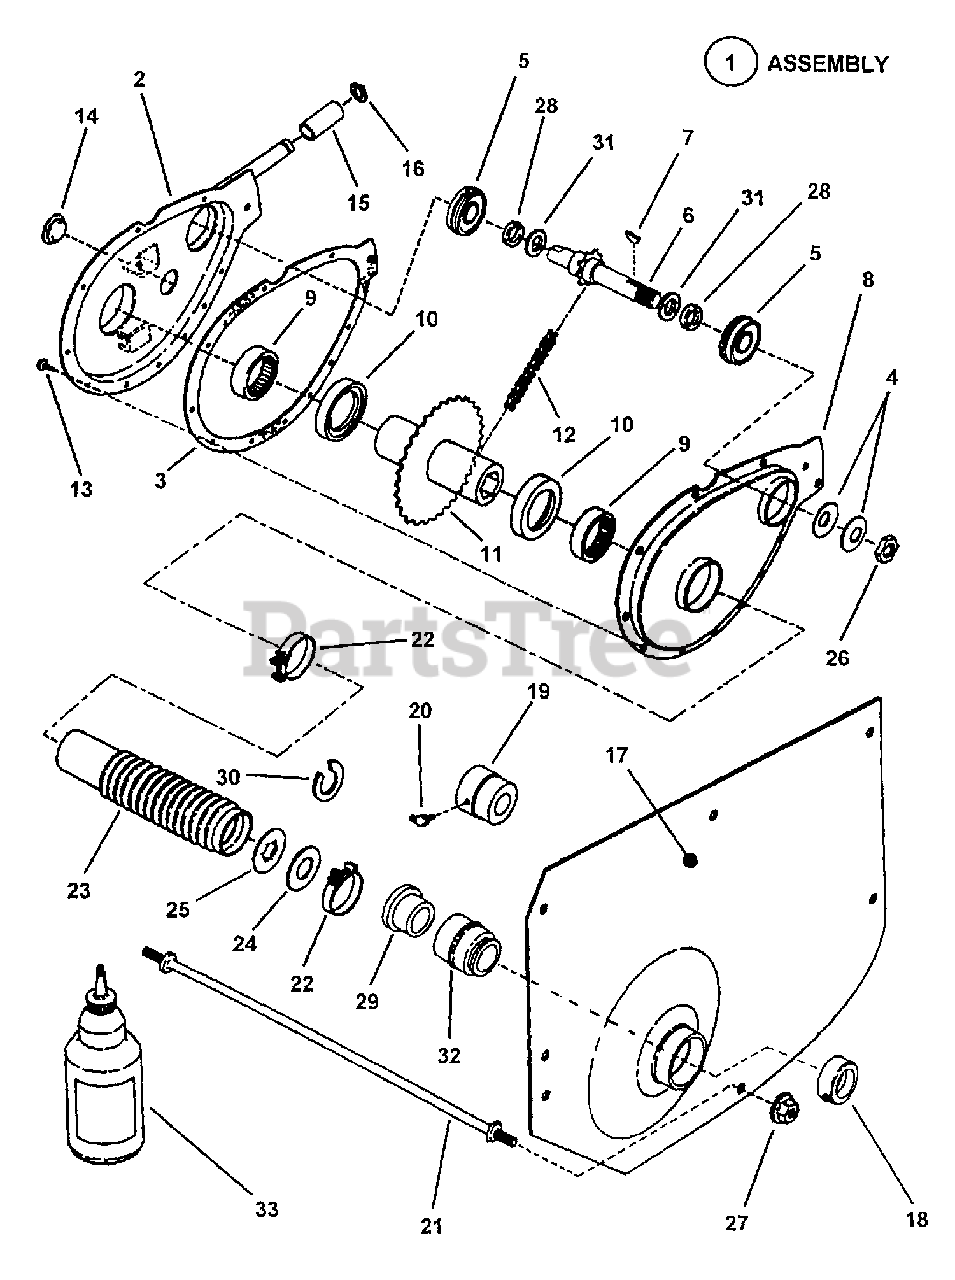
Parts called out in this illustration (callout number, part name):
1	ASSEMBLY, Chain Case
2	CASE, Sprocket
3	GASKET, Case Cover
4	WASHER, .640 I.D. Belleville
5	BEARING, Ball
6	SPROCKET & SHAFT
7	KEY, 1/8 x 5/8" Woodruff
8	COVER, Chain Case
9	BEARING, Needle
10	WASHER, Nylon Thrust
11	HUB & SPROCKET
12	CHAIN
13	SCREW, #10-24 x 1/2" Hex Washer Self-Tap (Torx)
14	PLUG, Oil Fill & Check
15	ROLLER
16	RING, 1/2" Heavy Duty External Retaining
17	FENDER, Left Hand
17	ASSEMBLY, Left Hand Fender
18	COLLAR, Lock
19	BEARING, Left Hand Fender
20	FITTING, Lube
21	ROD, Cross-Tie
22	CLAMP, Boot
23	BOOT, Oil Seal
24	WASHER, Thrust Nylon
25	WASHER, Thrust
26	NUT, 5/8-18 Hex Nyloc
27	NUT, 5/16-24 Hex Flange Lock
28	O-RING
29	SPACER
30	WASHER, Shim
31	WASHER, Shim
32	BALL BEARING, Left Hand Fender
33	GREASE, Transmission
